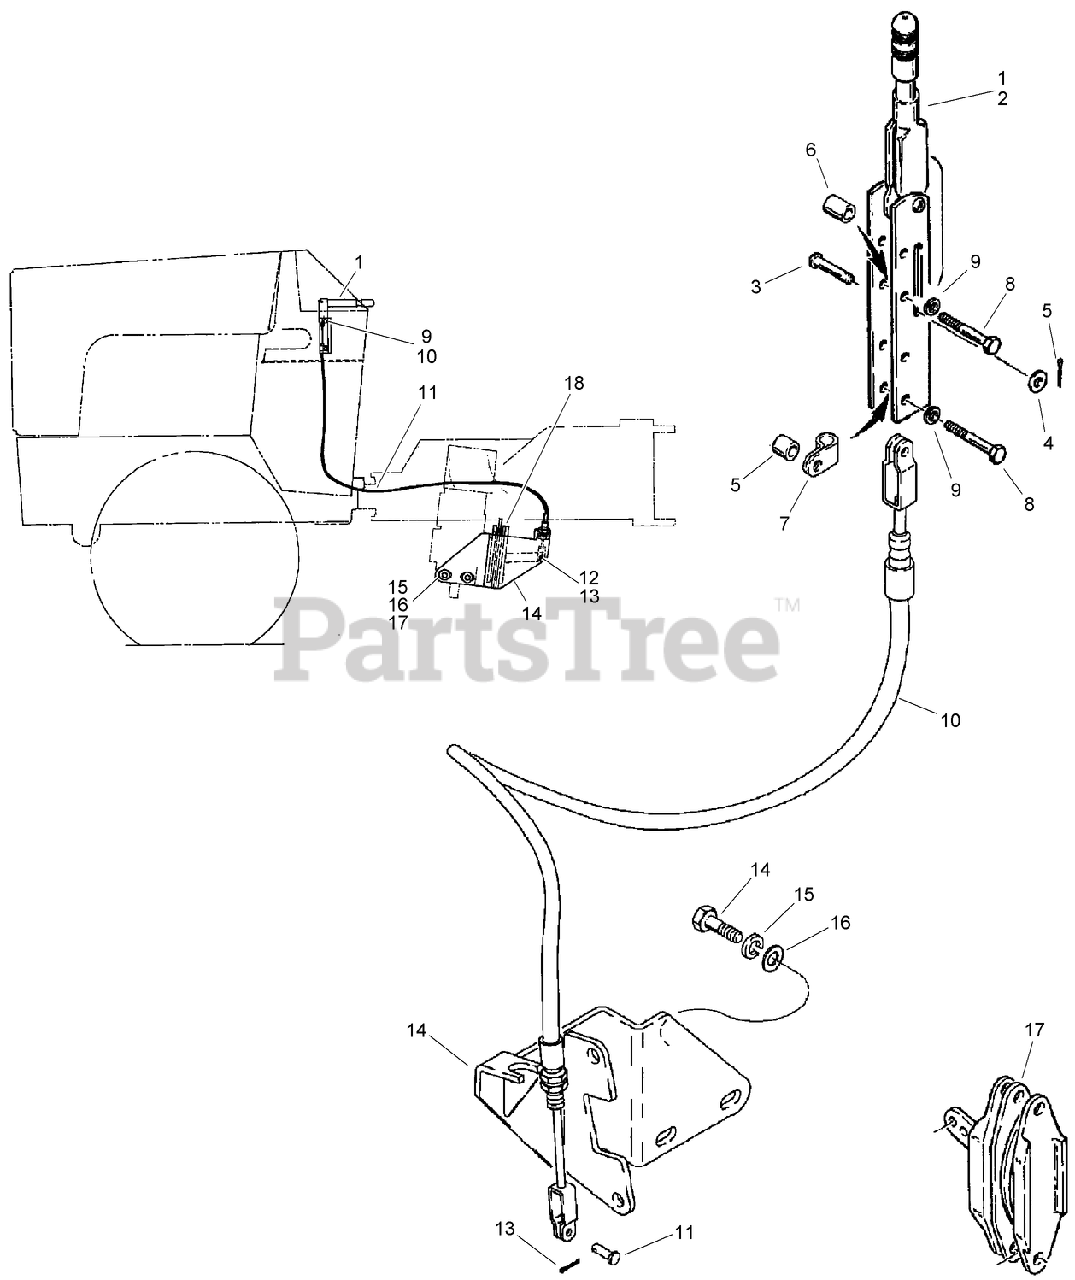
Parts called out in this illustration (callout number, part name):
1	LEVER-BRAKE
2	LEVER - Parking Brake
3	PIN - Clevis, Special
4	WASHER - Flat, 3/8 x 7/8 x 3/32 inch
5	PIN - Cotter .094 x .75 in ZN
6	SPACER-13 mm (1/2 inch) long
7	SPACER
8	CLAMP - Parking Brake Cable
9	BOLT-Hex, 5/16 NC x 1-1/2 inch
10	WASHER-Lock, 5/16 inch
11	CABLE-BRAKE
12	PIN
13	PIN-Cotter 0.062 x 0.75 in ZN
14	BRACKET - Mounting, Brake Caliper
15	BOLT-Hex Hd 1/2 x 1-1/4 GR5 ZND
16	WASHER-Spring Lock Reg 1/2 ZND
17	WASHER - .562 x 1.375 x .109 in CST ZND
18	CALIPER ASM
